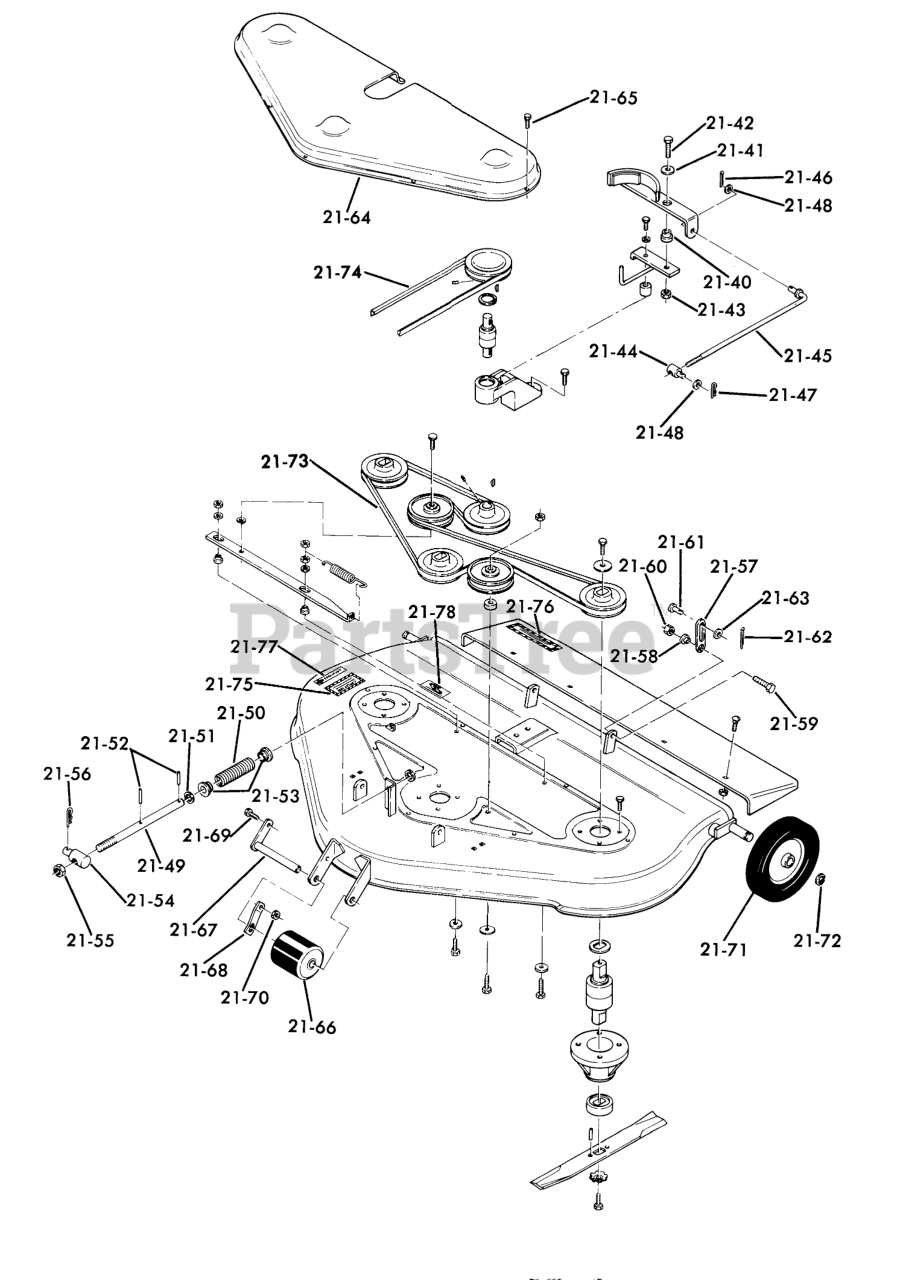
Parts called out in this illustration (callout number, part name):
21-40	SPACER
21-41	WASHER
21-42	BOLT
21-43	Nut
21-44	TRUNNION
21-46	Cotter Pin
21-47	Hairpin Cotter
21-48	Washer
21-49	Link Rod
21-50	SPRING
21-51	WASHER
21-52	SPIROL PIN
21-53	BUSHING
21-54	Trunnion
21-55	Hex Nut 7/16-14
21-56	Hairpin Cotter
21-57	BAR-LIFT LINK R
21-58	SPACER-LIFT LINK
21-59	Bolt
21-60	Nut
21-61	CLEVIS PIN
21-62	Cotter Pin
21-63	Washer
21-64	Belt Cover
21-65	Bolt
21-66	Roller
21-67	Roller Shaft
21-68	SPRING ROLLER STOP
21-69	H H C S
21-70	Nut
21-71	Wheel
21-72	E Ring
21-73	80" Mower Belt
21-74	BELT-40IN DRIVE
21-75	Caution Decal
21-76	Guard Decal
21-77	Decal-Edge of Cut
21-78	Belt Installation Decal
